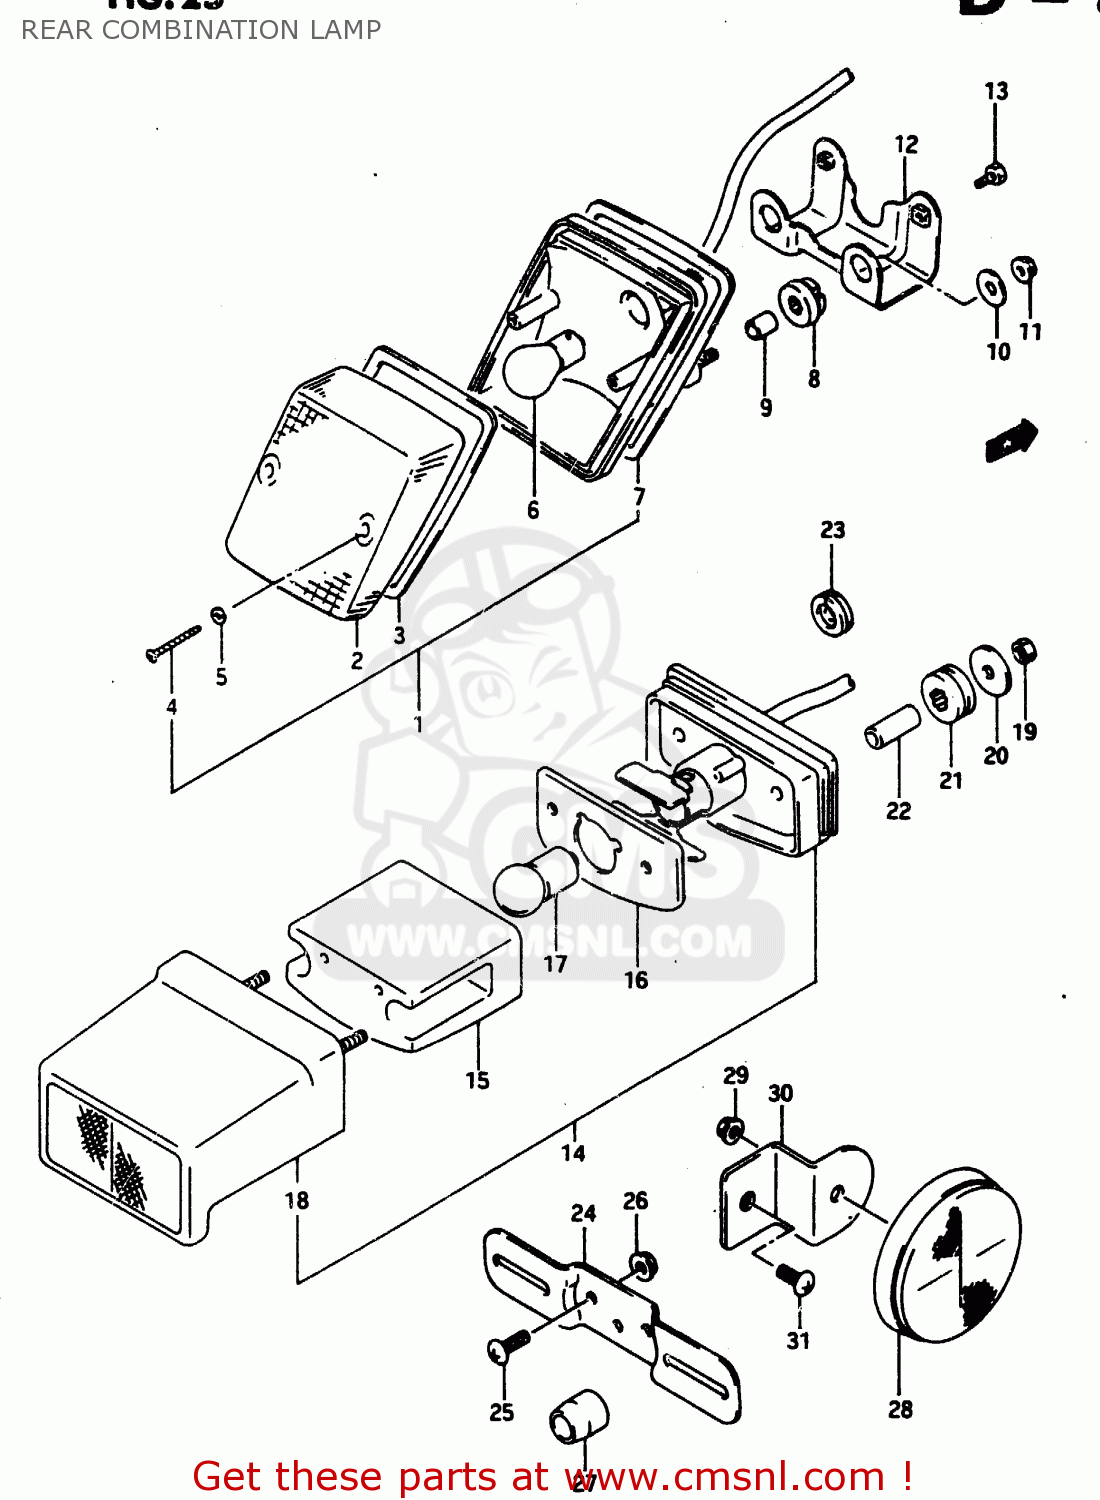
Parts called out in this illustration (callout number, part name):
1	LAMP ASSY, REAR COMBINATION
2	LENS,RR COMBI
3	GASKET,REAR COMBINATION LAMP
4	SCREW TAPP.
5	GASKET (NAS)
6	BULB(12V21/5W)
7	GASKET
8	CUSHION
9	SPACER (6.8X10X10)
10	WASHER (6.5X20X1.2)
11	NUT
12	BRACKET,REAR COMBINATION LAMP
13	BOLT
14	LAMP ASSY, LICENSE
15	LENS
16	GASKET,LICENSE LAMP (NAS)
17	BULB(12V5W,BF150-40160A)
18	REFLEX REFLECTOR & COVER
19	NUT
20	WASHER(4.3X20X1.4)
21	CUSHION
22	SPACER
23	GROMMET
24	BRACKET,LICENSE PLATE
25	SCREW
26	NUT
27	CUSHION
28	REFLECTOR,REFLEX
29	NUT
30	BRACKET,REAR SIDE,REAR,LEFT
31	SCREW
